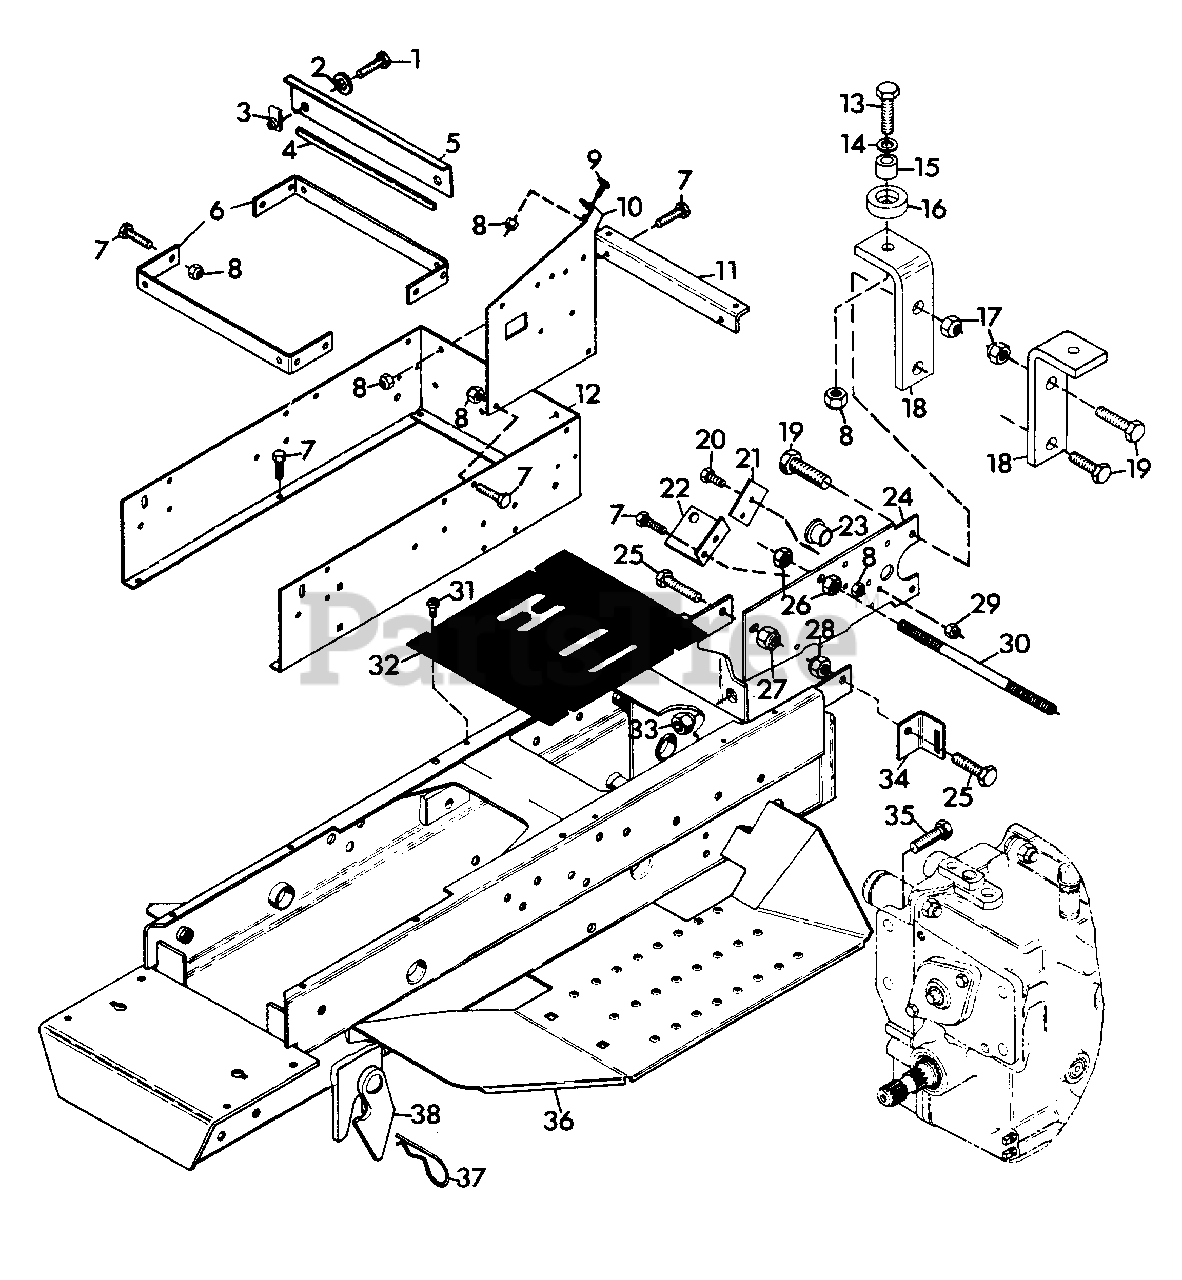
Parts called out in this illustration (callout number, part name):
1	BOLT, HEX 1/4-20X.875
2	WASHER, FLAT .281X.625X.065
3	NUT, RETAINER
4	MOULDING
5	BRACKET, FORWARD TANK
6	BRACKET, FUEL TANK
7	BOLT, HEX 1/4-20X.75
8	NUT LOCK 1/4-20
9	SCREW, MACHINE 1/4-20X.75 PAN HD.
10	BRACE, INSTRUMENT PANEL L.H.
10	BRACE, INSTRUMENT PANEL R.H.
11	BRACKET, INSTRUMENT PANEL
12	SUPPORT, INSTRUMENT PANEL
13	BOLT, HEX 1/4-20X1.25
14	WASHER, FLAT .312X.734X.065
15	BUSHING, .259X.375X.25
16	BUMPER, SEAT
17	NUT, LOCK 1/2-13
18	BRACKET, REAR HITCH
19	BOLT, HEX 1/2-13X1.50
20	BOLT, HEX 5/16-18X.75
21	BRACKET, BUSHING LOCK
22	BRACKET, INTERLOCK SWITCH
23	BUSHING, NYLON .76X1.00X.76 FLANGE
24	PLATE, FWD-REV MOUNTING
25	BOLT, HEX 3/8-16X1.25
26	NUT, HEX 1/2-13
27	NUT, LOCK 3/8-16
28	NUT, LOCK 3/8-16
29	NUT, LOCK 5/16-18
30	ROD, FRAME EXTENSION BRACE
31	SCREW, TAPPING 1/4-20X.625 PAN HD
32	PLATE, MANUAL CONTROL COVER
32	PLATE, HYDRAULIC CONTROL COVER
33	NUT, RIM
34	BRACKET, FENDER HOLD-UP
35	BOLT, HEX 1/2-20X1.50
36	WELDMENT, FRAME
37	PIN, HAIR
38	WELDMENT, MOWER BRACKET R.H.
38	WELDMENT, MOWER BRACKET L.H.
